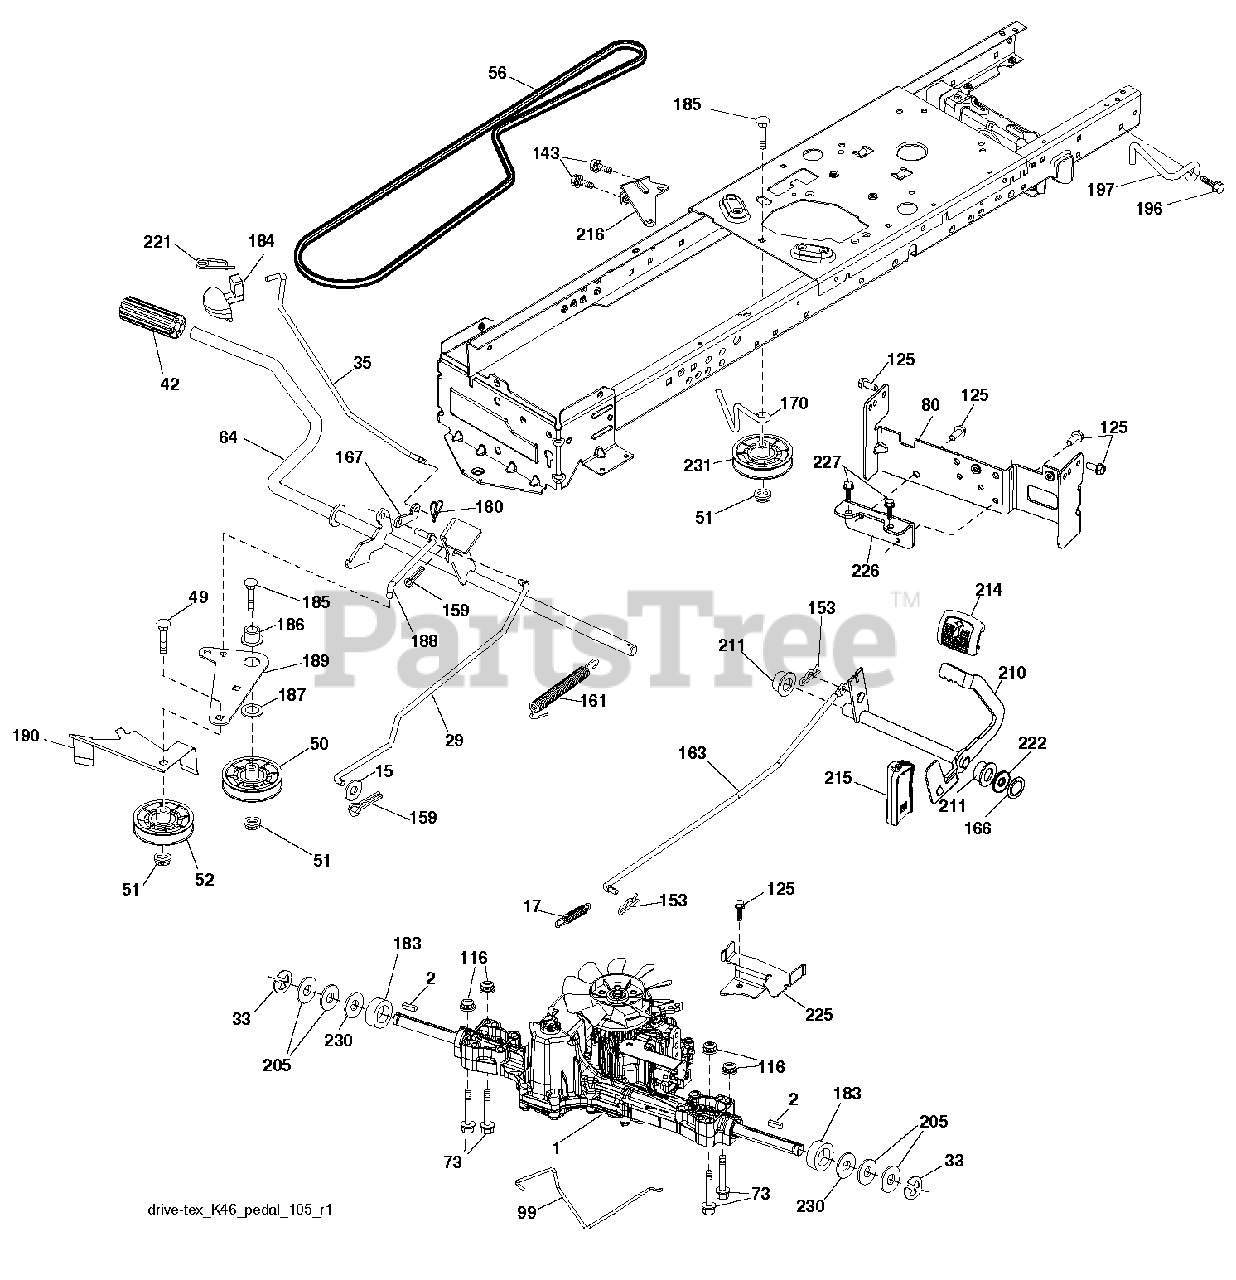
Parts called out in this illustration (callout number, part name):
2	SQUARE KEY
15	WASHER
17	SPRING.BRAKE.K46.GREEN
29	ROD.BRAKE.K46
35	ROD.CNTRL.PARK.PREDATOR.LT.TEX
42	PEDAL COVER T
50	IDLER.FLAT.910.OFFSET
51	NUT LOCK FLG 3/8-16 UNC
52	IDLER.V-GROOVE.910.OFFSET
56	V-BELT.MOWER.92.40.42/K46
64	SHAFT.ASM.PEDAL.BRK.CNTR
80	STRAP.TORQUE.K46.K57R.TT
99	ROD.SPRING.BYPASS.K46.LT.Z
116	NUT LOCK HEX FLANGE 5/16-18
125	SCREW
143	SCREW LT
153	RETAINER M
159	COTTER PIN
160	RETAINER CLIP
161	SPRING, RETURN LT
163	ROD.CONTROL.K57R.K46
166	NUT.PUSH.625
167	LATCH.BRAKE.SPRING
170	KEEPER.CENTER SPAN.1.688
183	SPACER AXLE
184	HANDLE.PARKING.BRK.PRED.LT.RED
186	SPACER.RETAINER
187	WASHER 12/32X2X10GA
188	RP LINK.CLUTCH.GROUND.DRIVE
189	BELLCRANK.GROUND.DRIVE.TEX.
190	KEEPER.BELLCRANK.DRIVE
196	SCREW 3/8-16X1
197	LINK.CLUTCH.ANIT-ROTAT
210	ROCKER.ASM.PEDAL.CONTR
211	BEARING.NYLON
214	PEDAL.FORWARD.PAD.TEX
215	PEDAL.REVERSE.TEX.GT.4
216	BRACKET.PULLEY.IDLER.W/TEX
221	RETAINER.SPRING.CLIP.H
222	WASHER 21/32 X 1-1/4 X 10 GA.
225	KEEPER.BELT.TRANSAXLE.K46
226	BRACKET.MOUNT.TORQUE.K46.TLT
227	SCREW
230	WASHER.HARDENED
231	IDLER.V-GROOVE.1.688.OFFSET
